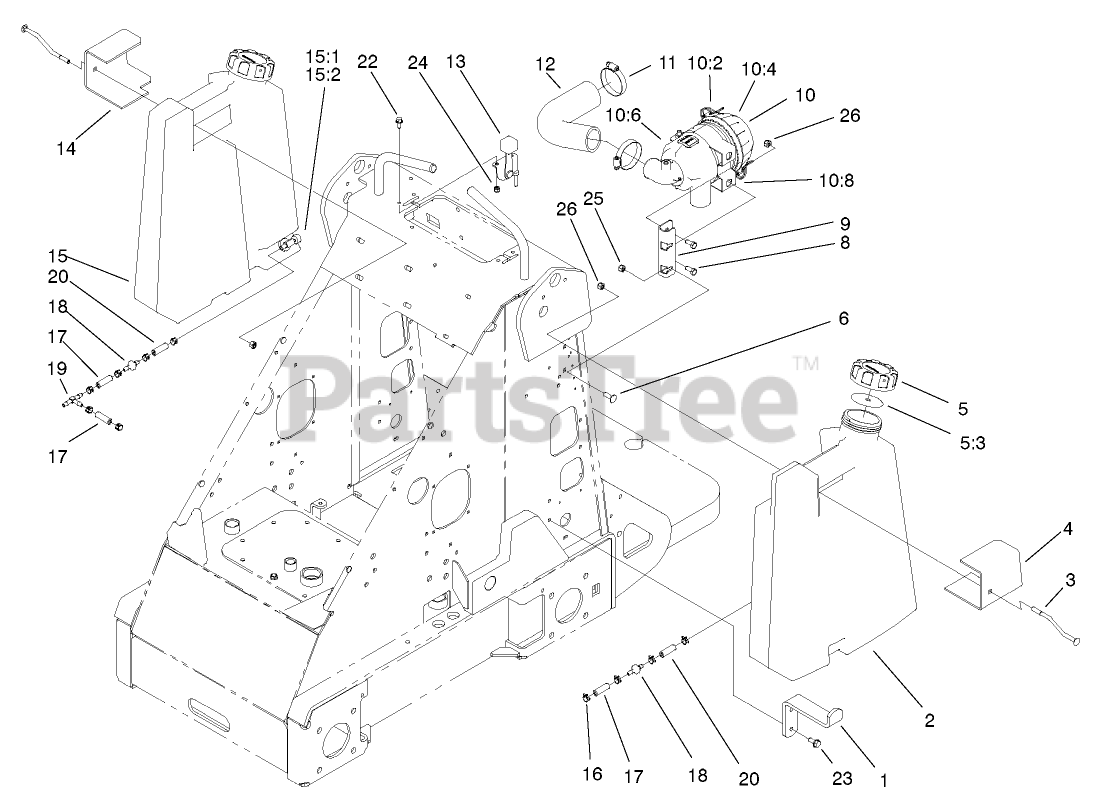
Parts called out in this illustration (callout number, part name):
1	MOUNT-BOTTOM, TANK
2	Fuel Tank ASM
3	BOLT-MOUNT
4	PLATE-MOUNT, LEFT
5	CAP-FUEL, GAS
5:3	GASKET-VENTED
6	BOLT-CARR
8	SCREW-HH
9	MOUNT-CLEANER, AIR
10	AIR CLEANER ASM
10:2	CLIP-CLEANER, AIR
10:4	COVER
10:6	HOUSING
10:8	MOUNTING BRACKET ASM
11	CLAMP-HOSE
12	HOSE-AIR
13	CONTROL-CHOKE / THROTTLE
14	PLATE-MOUNT
15	Fuel Tank ASM
15:1	BUSHING
15:2	VALVE-FUEL
16	CLAMP-HOSE
17	HOSE-FUEL
18	VALVE-CHECK, FUEL
19	FITTING-TEE, BARBED
20	HOSE-FUEL
22	SCREW-HHF
23	SCREW-HWHTF
24	NUT-LOCK, NI
25	NUT-HF
26	NUT-LOCK, NI
